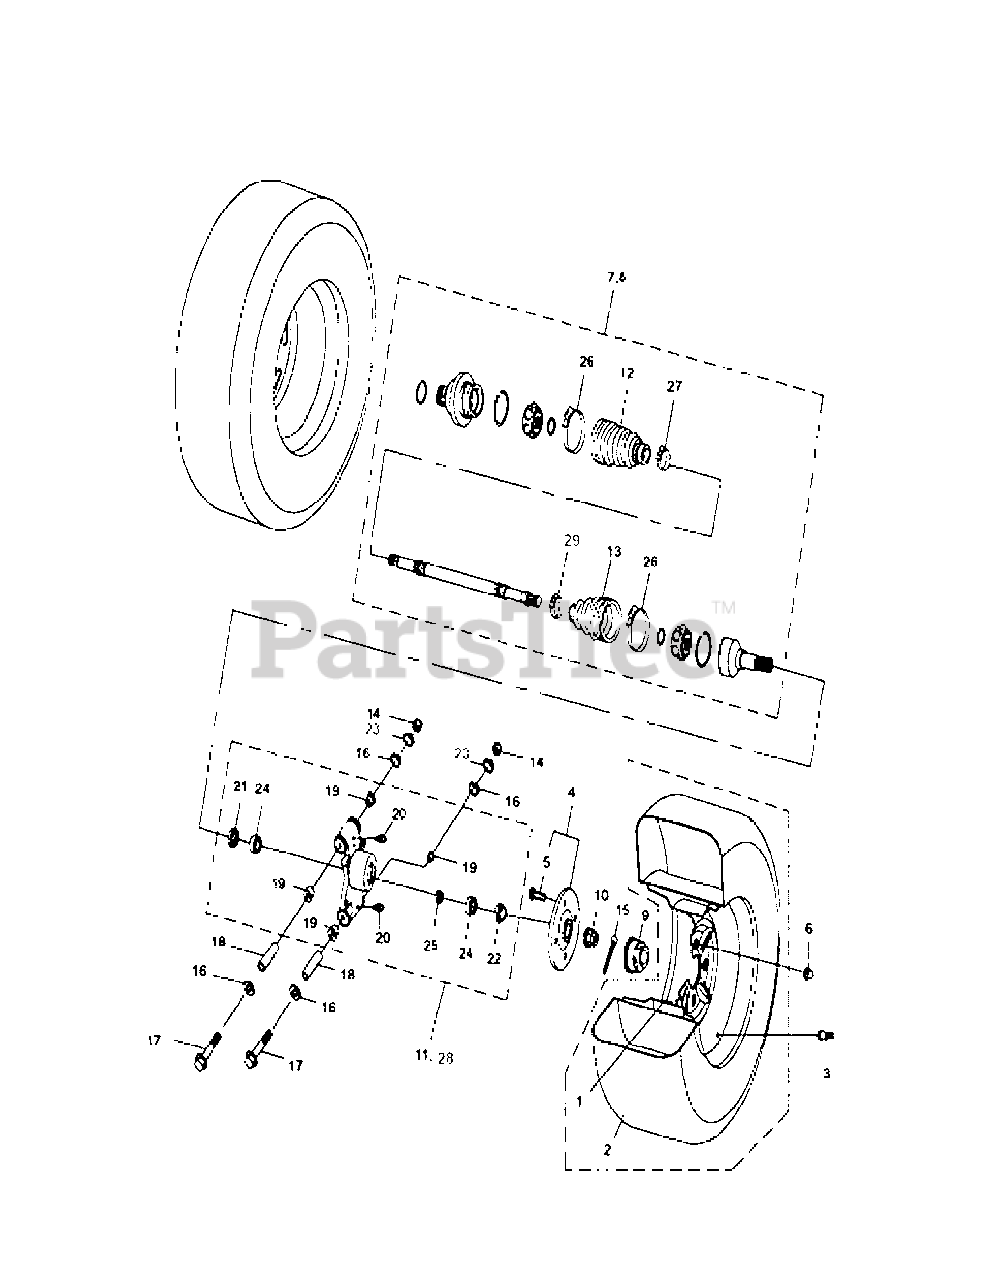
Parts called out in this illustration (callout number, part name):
1	Rear Alu. Wheel F116
3	Cycle Valve
4	Rear Hub
6	Nut M10
7	Rear Left C.V Axle
8	Rear Right C.V Axle
9	Wheel Caps III
11	Rear Right Knuckle Assy
12	Inner Rubber Dust-P Cover (C-1520)
13	Inner Rubber Dust-P Cover (C-1605)
14	Hexagon flange nut M10×1.25
15	Cotter Pin 3.2×50
16	Dust P. Cover
17	Bolt M10×1.25×110
18	Axle Sleeve, Liner
19	Sleeve For Knuckle
20	Refueling Nozzle M6
21	Inner Oil Seal , Rear Knuckle 38×62×8
22	Outer Oil Seal, Rear Knuckle 42×62×7
23	Washer 13X24X2
24	Bearing 6206, Rear Knuckle
26	CV Boot Proof Clamp A
27	CV Boot Proof Clamp B
28	Rear Left Steering Knuckle Assy
